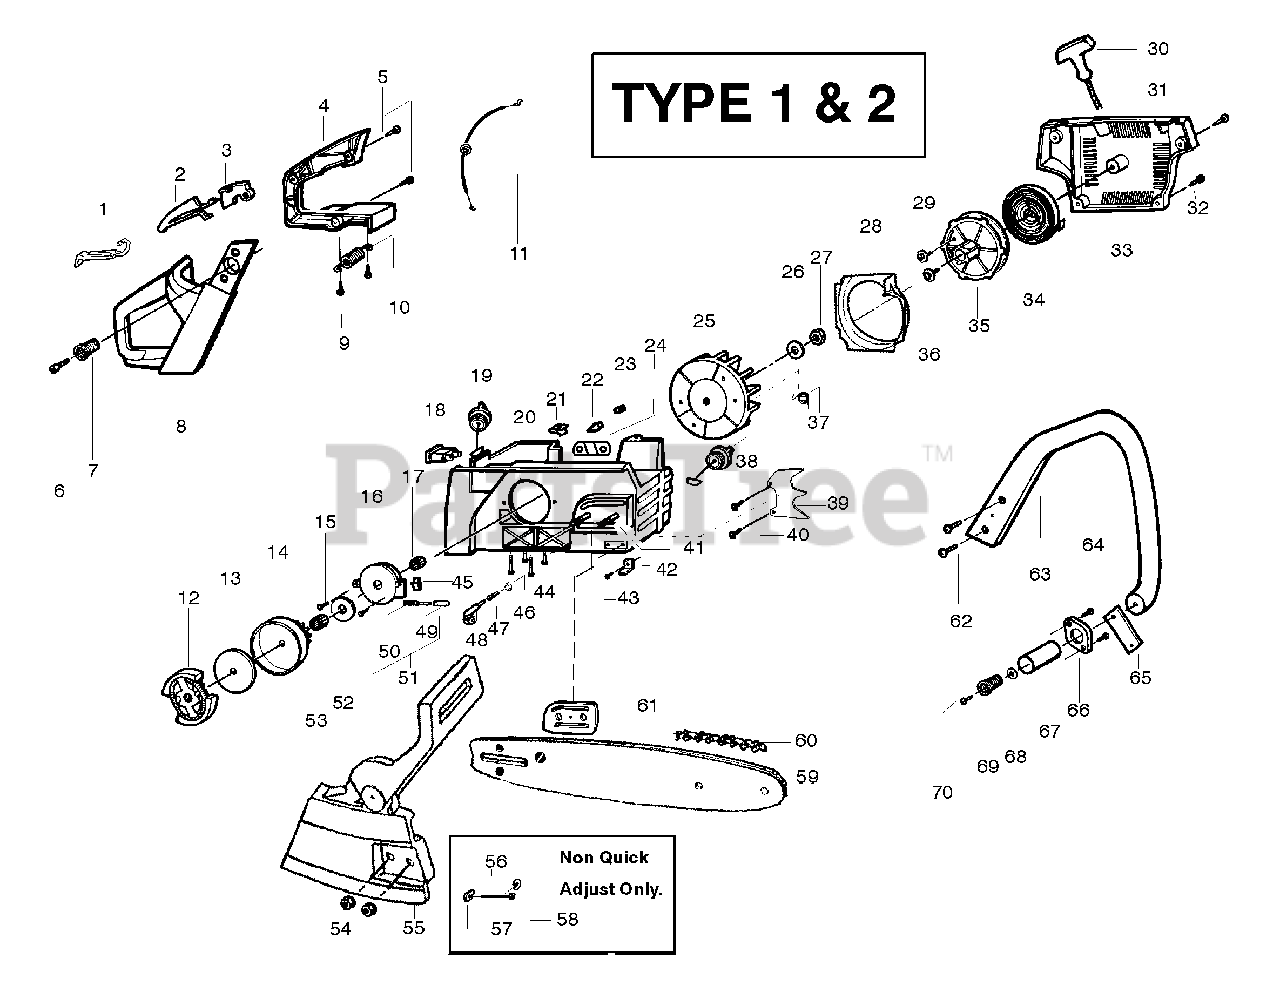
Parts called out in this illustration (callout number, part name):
1	Choke Lever
2	Throttle Lockout
3	Throttle Trigger
4	Handle Cover
7	Spring - Isolator
8	Rear Pro Handle
10	Isolator Spring
11	Throttle Cable
12	Clutch Ass'y.
13	Clutch Washer
14	Kit - Clutch Drum & Bearing
16	Oil Pump Hsg.
17	Oil Pump Worm
18	Switch Kit
19	Fuel Cap Ass'y.
20	Chassis Ass'y.
21	Speed Nut
22	Check Valve
23	Vent Plug
24	Bar Stud Plate
25	Flywheel Ass'y.
28	Baffle Plate
30	Starter Handle
31	Rope Kit
33	Fan Hsg. Ass'y. Kit
34	Recoil Spring
35	Kit - Starter Pulley
37	Spring - Starter Dog
38	Oil Cap Ass'y.
39	Assy. - Spike
40	Screw
41	Bar Bolt
42	Chain Catcher
45	Oil Seal
46	Plug-Oiler Filter
47	Oil Filter
48	Oil Pick-up
49	Oil Pump Barrel
50	Plunger & Gear Ass'y.
51	Oil Pump Ass'y.
52	Thrust Washer
53	Clutch Bearing
54	Bar Mounting Nut
55	Assy-Chainbrake
56	Retainer-Bar Adjust
57	Bar Adjusting Pin
58	Kit - Bar Adjust
59	Bar 16"Standard
59	Bar 18"Standard
59	Bar 20"Standard
59	Bar 20"Quick Adjust
60	Chain 16"(66/.325-.050")
60	Chain 18"(72/.325-.050")
60	Chain 20"(78/.325-050")
61	Bar Plate
63	Handle
65	Front Strap
66	Isolator Plate
67	Spring Sleeve
69	Isolator spring
